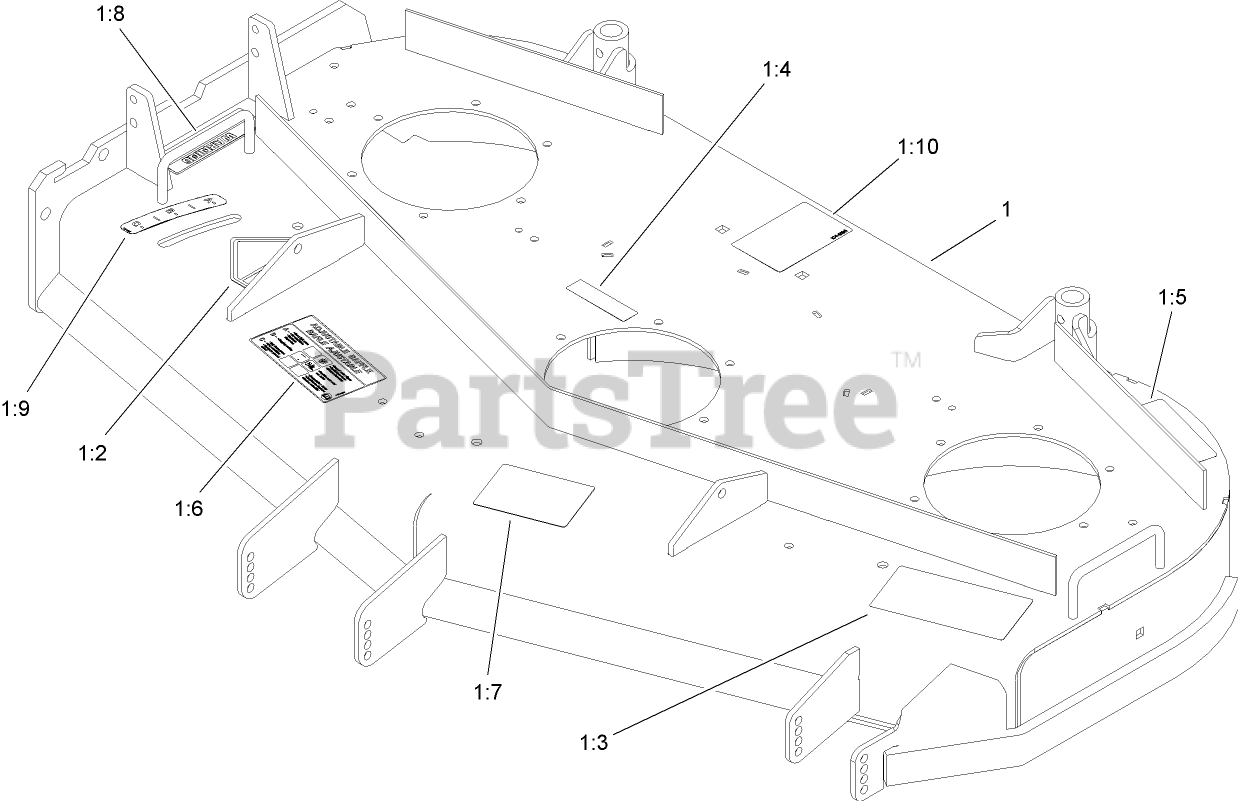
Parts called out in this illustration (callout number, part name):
1	48 INCH DECK ASM
1:2	DECAL-DANGER
1:3	DECAL-DANGER, THROWN OBJECT
1:4	DECAL-COVER, MISSING
1:5	DECAL-TORQUE
1:6	DECAL-ADJUSTMENT, BAFFLE
1:7	DECAL-SCALP, ANTI
1:8	DECAL-WARNING
1:9	DECAL-SETTING, BAFFLE
1:10	DECAL-ROUTING, BELT
